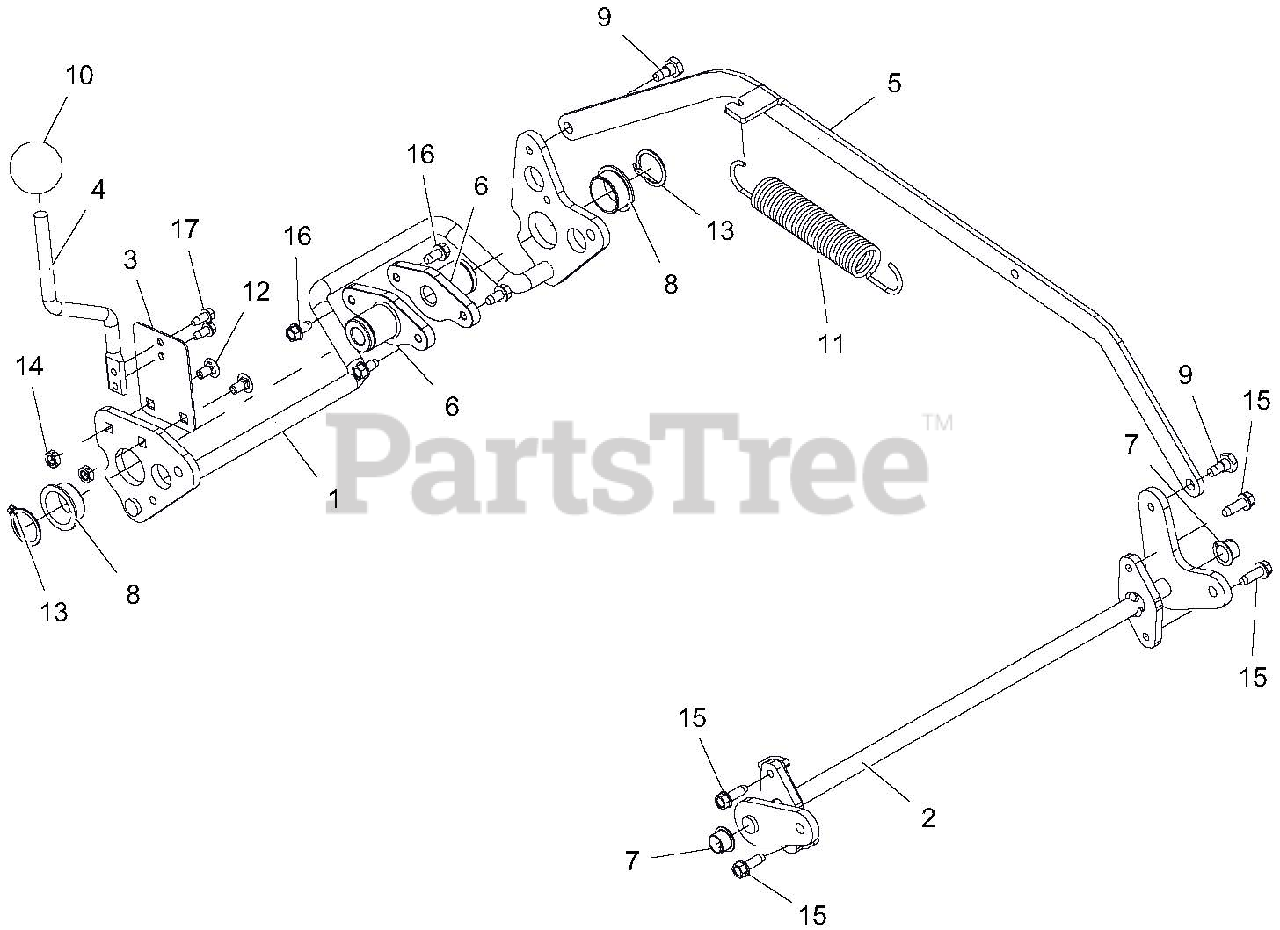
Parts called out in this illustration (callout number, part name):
1	WLDMT, REAR AXLE
2	WMT, LM FRONT AXLE
3	PLATE, HOC SPRING
4	LEVER, HOC ADJUSTMENT
5	LINK, HOC CONNECT
6	HUB, LM REAR AXLE
7	BUSHING, POLYLINER-.50 SPLIT
8	BSHG-FLG 1.0X1.125X.50X1.375 R
9	BOLT, SHLDR .320X.210X.25-20
10	KNOB,BALL -BLACK 1.47" .375-16
11	SG-TENS .121X1.00X6.5 WLD 12
12	@BLT-RDHDSQNK .25-20X.50 G5YZ
13	RG-RTNG-EXT 1.00X.042
14	NUT-LK-CTR JAM .25-20 YWZC
15	SCR-TAP-PM .25-20X.75 TR YWZ
16	SCR-TAP .25-20X.50 HWH TR YWZ
17	@SCR-TAP 12-24X.50 HWH TR YWZC
